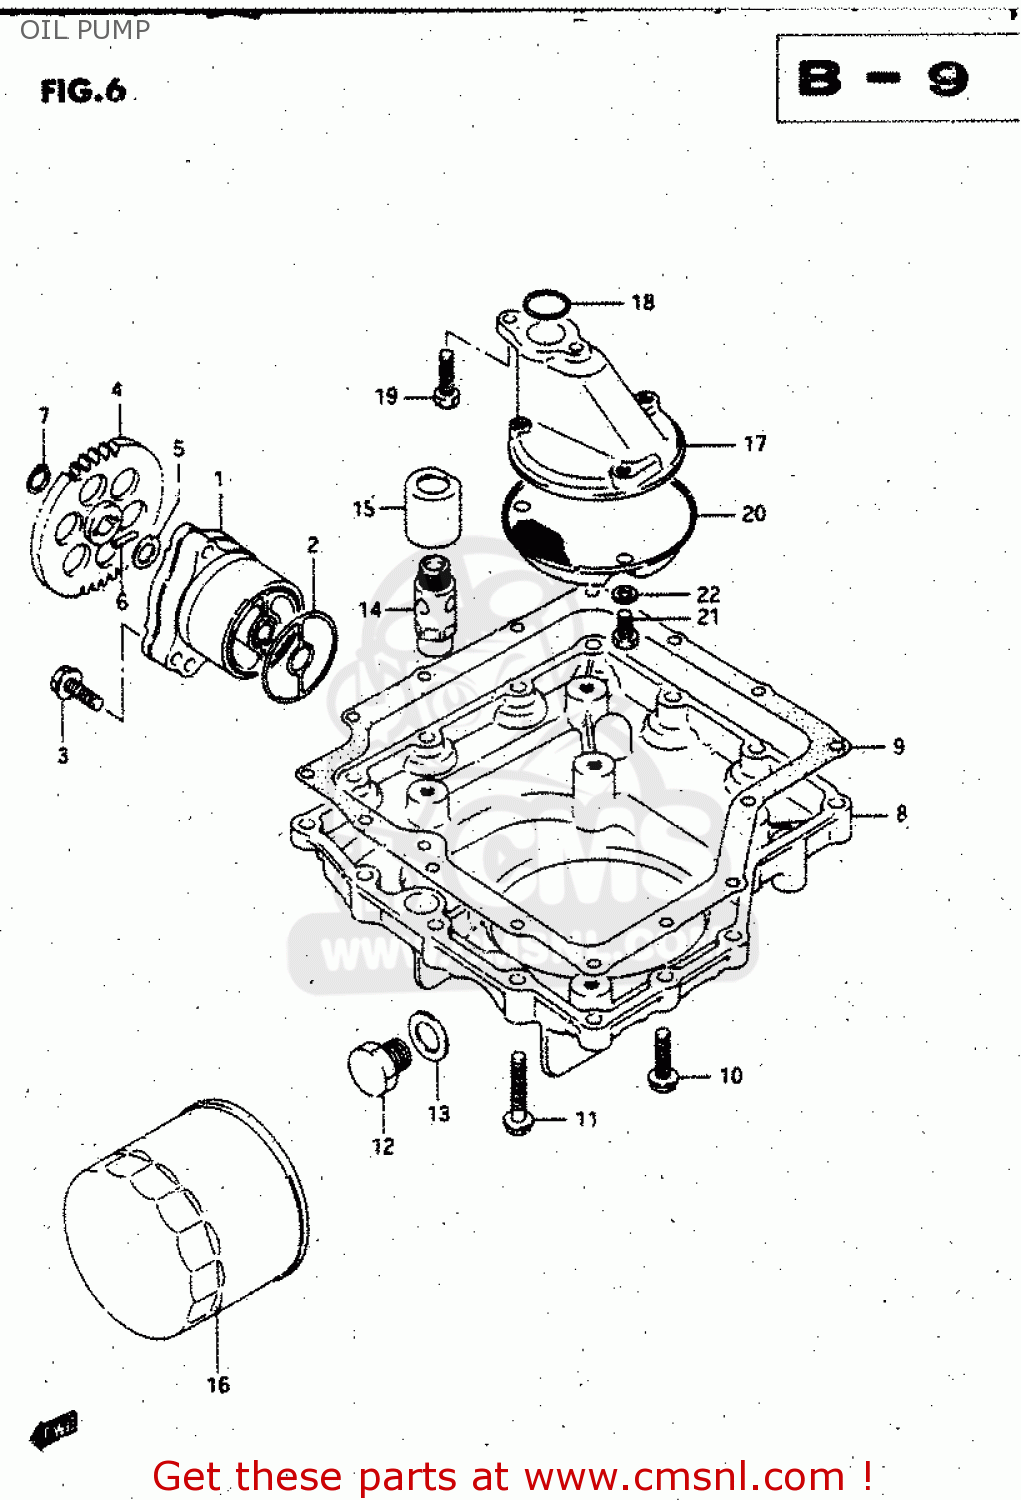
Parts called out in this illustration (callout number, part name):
1	PUMP ASSEMBLY,ENGINE OIL
2	O RING,OIL PUMP
3	BOLT
4	GEAR,OIL PUMP DRIVEN
5	SHIM
6	PIN(4X15.8)
7	CIRCLIP
8	PAN,OIL
9	GASKET,OIL PAN (MCA)
10	BOLT
11	BOLT
12	PLUG
13	GASKET(14X19.2X2) (NAS)
14	VALVE ASSY,OIL RELIEF
15	GUIDE, VALVE
16	FILTER,OIL
17	PROTECTOR,OIL STRAINER
18	O RING(D:3.2,ID:17.8)
19	BOLT,REAR
20	STRAINER,ENGINE OIL
21	BOLT
22	WASHER,LOCK
